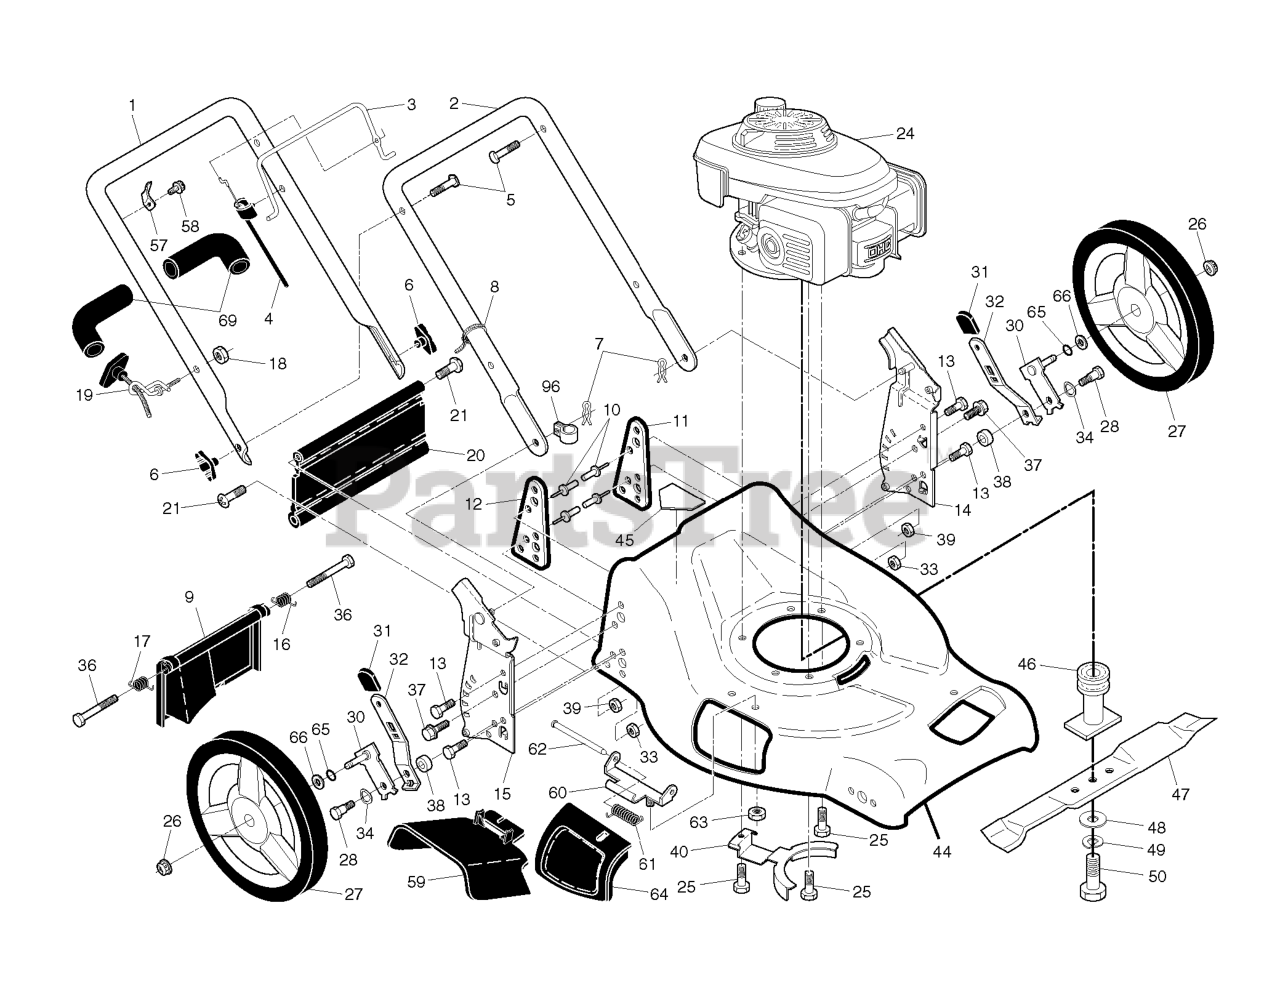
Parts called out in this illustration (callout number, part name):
1	HANDLE.ASM.UPPER.W/GRIP
2	LOWER HANDLE
3	BAIL.CONTROL.MZR.BS.ORANGE
4	CABLE.ASM.ZONE.CONTROL
5	BOLT, HANDLE 5/16-18X1.75
6	KNOB, DEFLECTOR
7	HAIRPIN COTTER
8	TIE GUIDE
9	REAR DOOR ASSEMBLY
10	RIVET BLIND
11	SUPPORT BRACKET LH
12	BRACKET.SUPRT.RH.21.FWGD
13	SCREW 14-20 X 5/8
14	RP BRACKET.ASM.HNDL/HW.LT.21.
15	BRACKET.ASM.HNDL/HW.RT.21.PNT
16	SPRING.REAR.DOOR.EZ.21.LT
17	SPRING.REAR.DOOR.EZ.21.RT
18	NUT
19	RB GUIDE.ROPE.STD.BLK.ZIN WSL
20	SKIRT.REAR.21 FWGD.BLACK
21	HINGE SCREW
25	BOLT 3/8-16X1-1/8
26	NUT.HEX.FLANGE.3/8-16.LOCKNUT
27	WHEEL ASSY
28	SHOULDER BOLT 5/16-18
30	ARM.ASM.AXLE.REAR.5/9.POS.BZP
31	SELECTOR KNOB
32	SELECTOR SPRING
33	NUT.71038.31-18.HEX.NYLOCK
34	WASHER.CURVED.CYLINDRICAL
37	BOLT.FIN.HEX.5/16-18X3/4
38	SPACER.HEIGHT.ADJUSTER
39	NUT.FLANGE.5/16
40	BRACKET.KEEPER.BELT
44	HOUSING.21.FWD.ORANGE.WALK
45	DANGER DECAL
46	RP ADAPTER.BLADE.25MM.21F
47	BLADE.21.PUSH/RWGD/FWGD
48	WASHER,HARDEN
49	LOCKWASHER
50	SCREW, HEX HD 3/8-24 X 1-3/8
57	BRACKET.UPSTOP.RT
59	DEFLECTOR.CLIPPIN.21.FGD
60	BRACKET.ASM.HINGE.21.FWGD.
61	SPRING.TORSION
62	ROD.HINGE.21
63	LOCKNUT.NYLOC.1/4-20
64	DOOR.MULCH.21.REAR.FWGD
65	O-RING..070X.487.NEOPRENE
66	WASHER.FLAT.1/2
69	GRIP.HANDLE.FOAM.WIDE.(1 SIDE)
96	CLIP.CABLE.BLK
